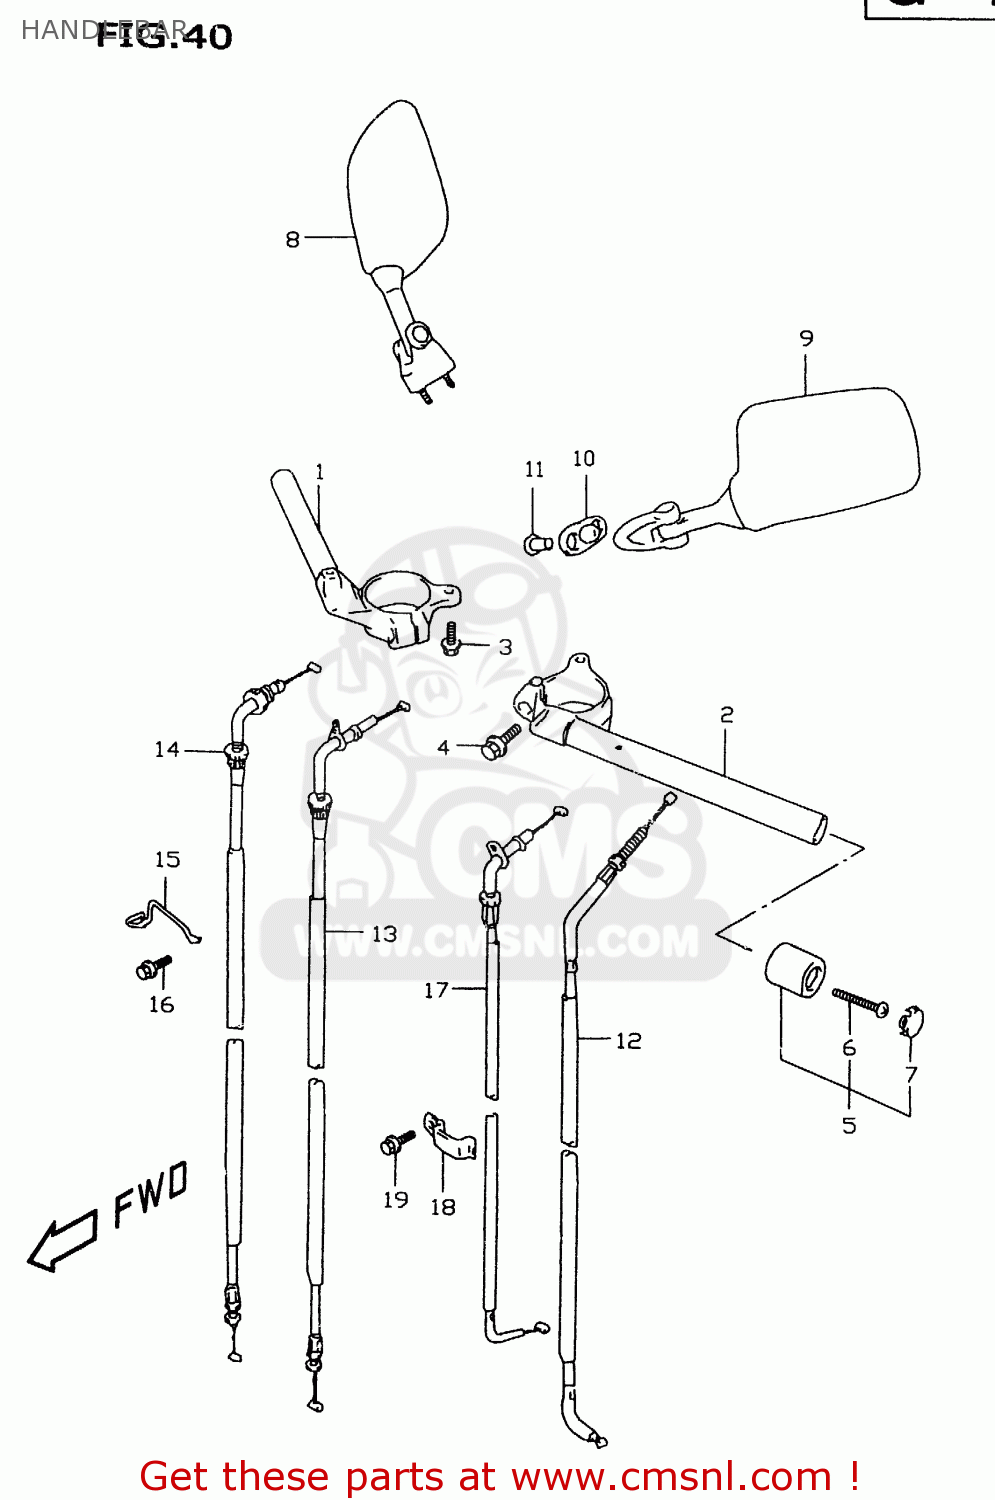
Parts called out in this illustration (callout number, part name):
1	HANDLEBAR,R
2	HANDLEBAR,L
3	BOLT
4	BOLT(8X30)
5	BALANCER SET,HANDLEBAR
6	SCREW
7	CAP,BALANCER
8	MIRROR ASSY,RR VIEW,R
9	MIRROR ASSY,RR VIEW,L
10	CUSHION,RR VIEW MIRRORR
11	NUT,RR VIEW MIRROR
12	CABLE ASSY,CLUTCH
13	CABLE ASSY,THROTTLE NO.1
14	CABLE ASSY,THROTTLE NO.2
15	GUIDE,THROTTLE CABLE
16	BOLT
17	CABLE,STARTER
18	CLAMP
19	BOLT
